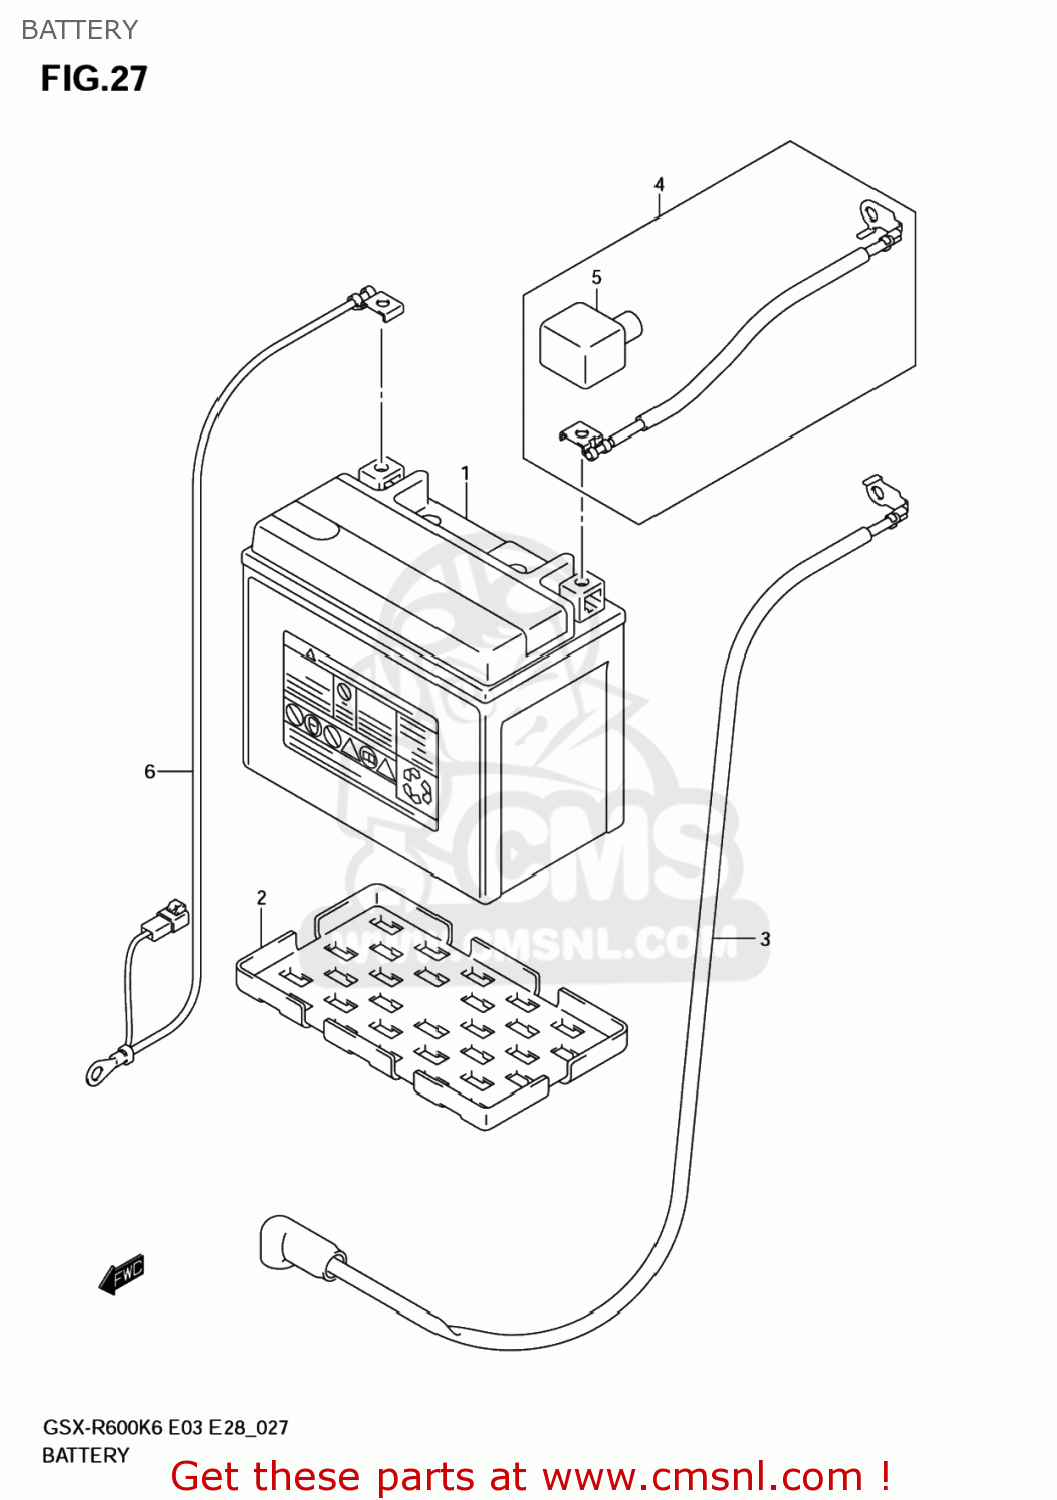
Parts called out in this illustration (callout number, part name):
1	BATTERY ASSEMBLY (12V) FTX
2	PROTECTOR,BATTERY
3	WIRE,STARTER MOTOR LEAD
4	WIRE,BATTERY PLUS LEAD
5	CAP,BATTERY PLUS
6	WIRE,BATTERY MINUS LEAD
